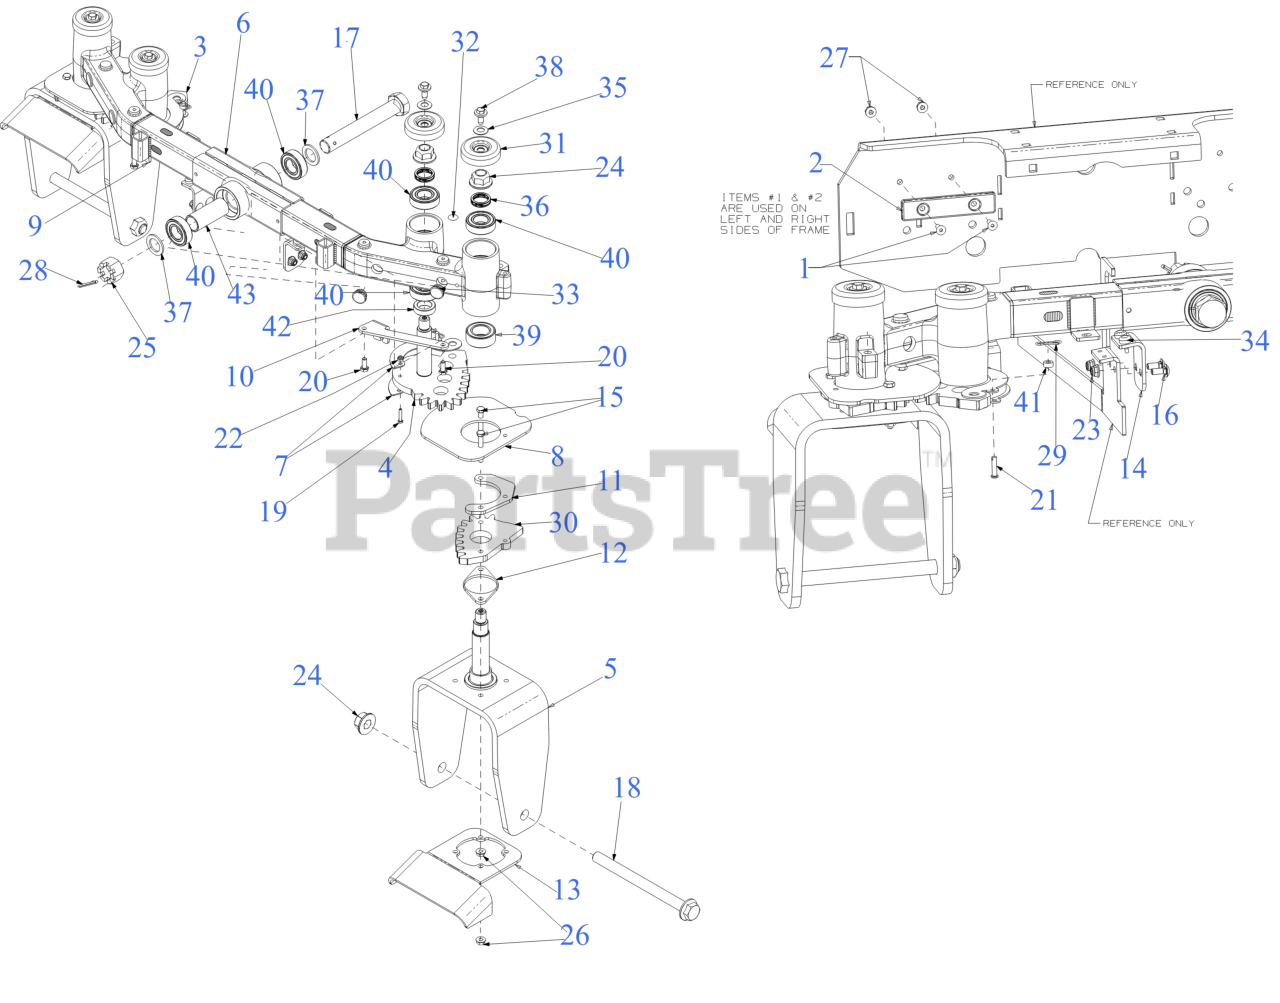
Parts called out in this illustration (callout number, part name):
1	SCREW-FLAT HEAD CA
2	PLATE-LIFT WEAR
3	LEFT HAND STEERING GEAR ASSEMBLY
4	RIGHT HAND STEERING GEAR ASSEMBLY
5	YOKE ASSEMBLY
6	AXLE ASSEMBLY
7	CABLE BEAR MOUNTING BRACKET
12	LOWER GEAR SPACER PLATE
14	AXLE BRACKET
15	HEX SCREW 5/16-18 x 2.25 GR5
16	CARRIAGE BOLT 5/16-18 x .75
17	HEX HEAD SCREW (1-14 x 7 GR5)
18	SCREW 3/4-16 x 9.00 GR5
19	SCREW #10-24 x 1.00 GR5.1
20	SCREW 5/16-18 x .750
21	CLEVIS PIN .25 x 1.00
23	FLANGE LOCK NUT 5/16-18
24	FLANGE LOCK NUT 3/4-16 TOP LOCK
25	CASTLE NUT 1.0-14 GR5
26	HEX FLANGE NUT
27	LOCK NUT 1/4
28	SPLIT COTTER PIN 5/32 X 2.00
29	BOW TIE COTTER PIN 1/4-5/16
30	STEERING GEAR YOKE
31	AXLE CAP 2.5"
32	RATCHET CLIP
34	BUMPER, .62 DIA x .3
35	BELL WASHER
36	WAVE WASHER
37	FLAT WASHER 1.005 x 1.570 x 0.125
39	BALL BEARING 30x52x20
40	BALL BEARING (1.0 x 52 x 15)
43	SPACER 1.00 x 1.25 x 2.99
